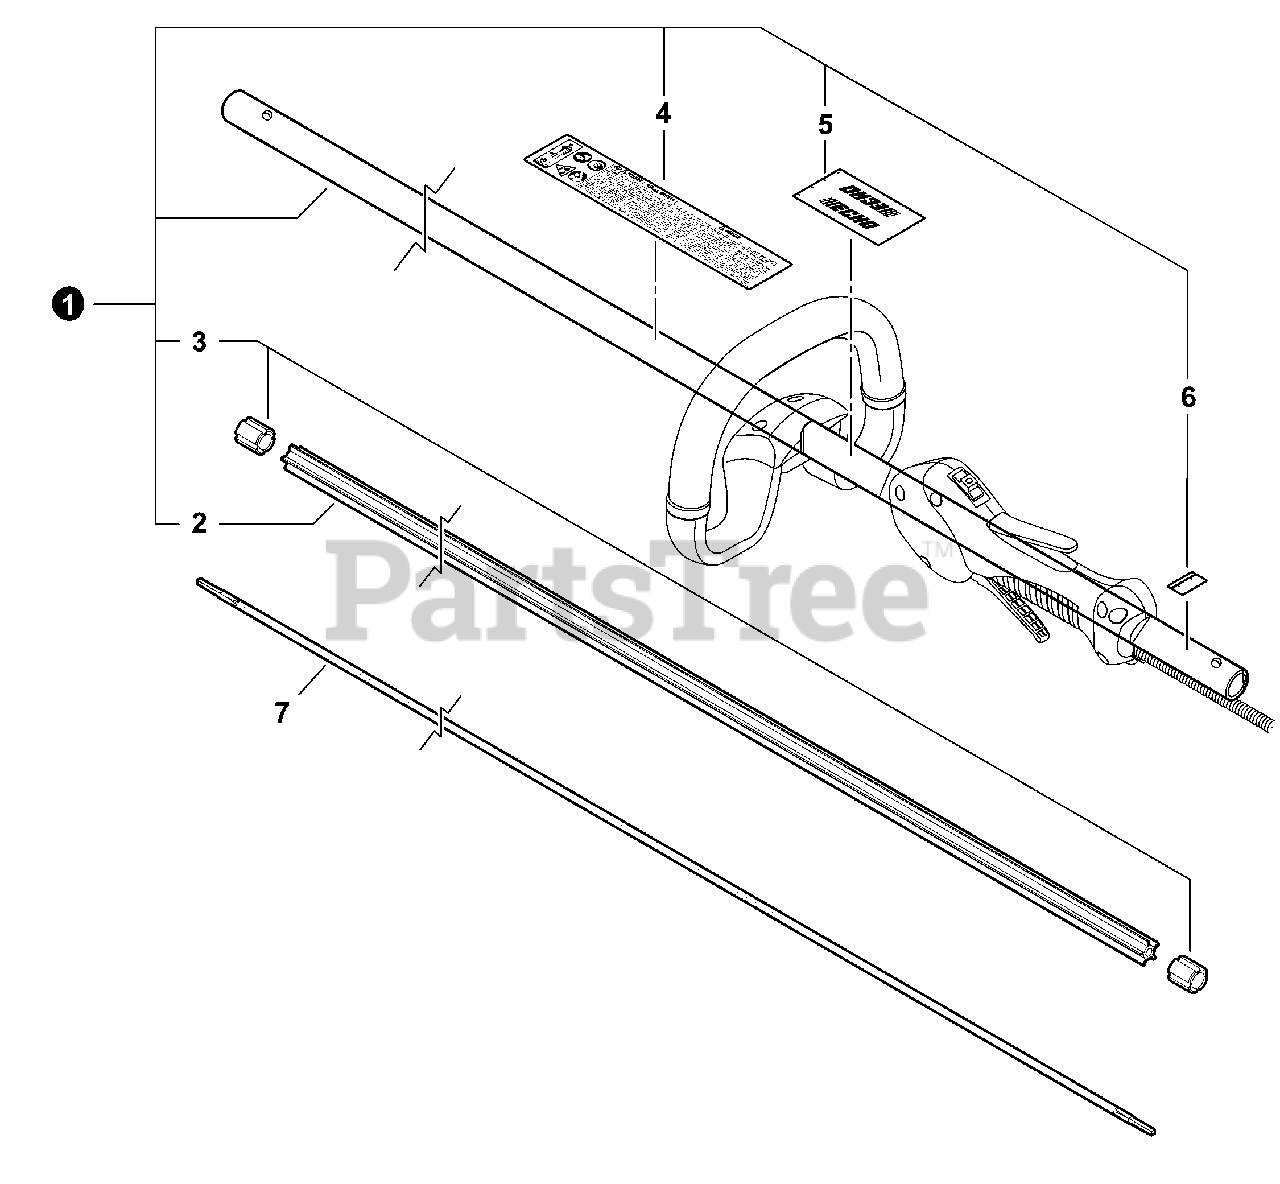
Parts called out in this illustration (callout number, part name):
1	MAIN PIPE ASY
2	LINER - FLEXIBLE
4	LABEL - CAUTION
5	LABEL - HANDLE LOCATION
6	LABEL - ALIGNMENT
7	DRIVESHAFT - FLEXIBLE
